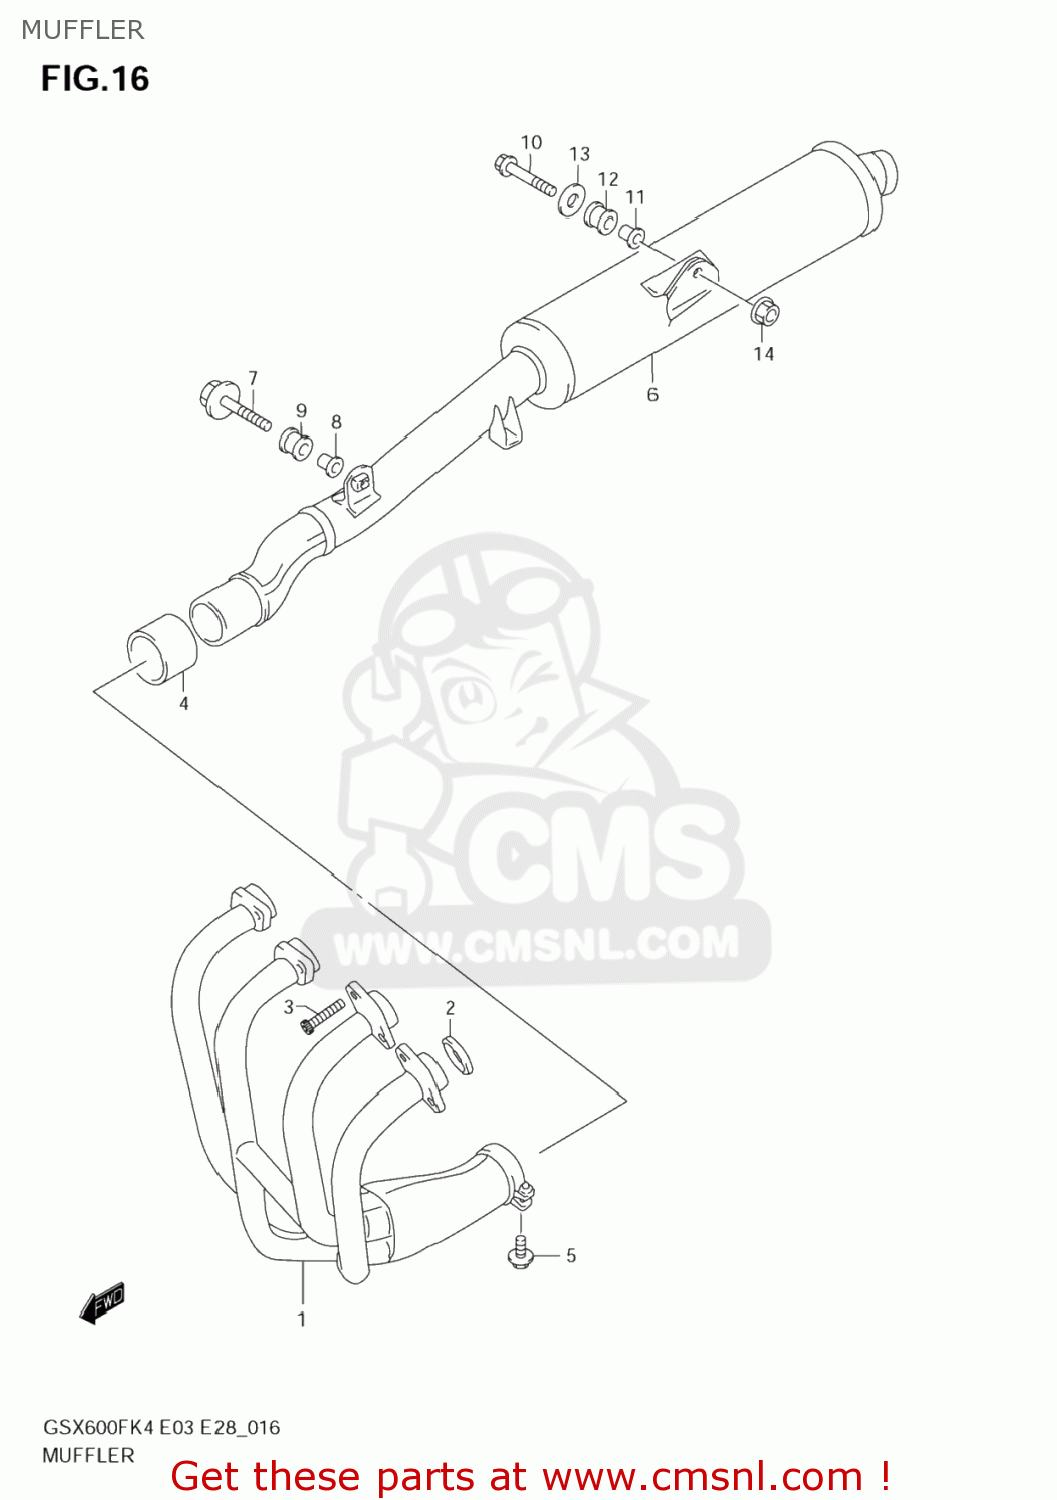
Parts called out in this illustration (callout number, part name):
1	EXHAUST
2	GASKET,EXHAUST (NAS)
3	BOLT
4	CONNECTOR,MUFFLER
5	BOLT
6	MUFFLER
7	BOLT 8X45
8	SPACER(8.6X12X24.2)
9	CUSHION
10	BOLT(8X45)
11	SPACER(8.6X12X27.1)
12	CUSHION
13	WASHER (8.5X33X1.6)
14	NUT
